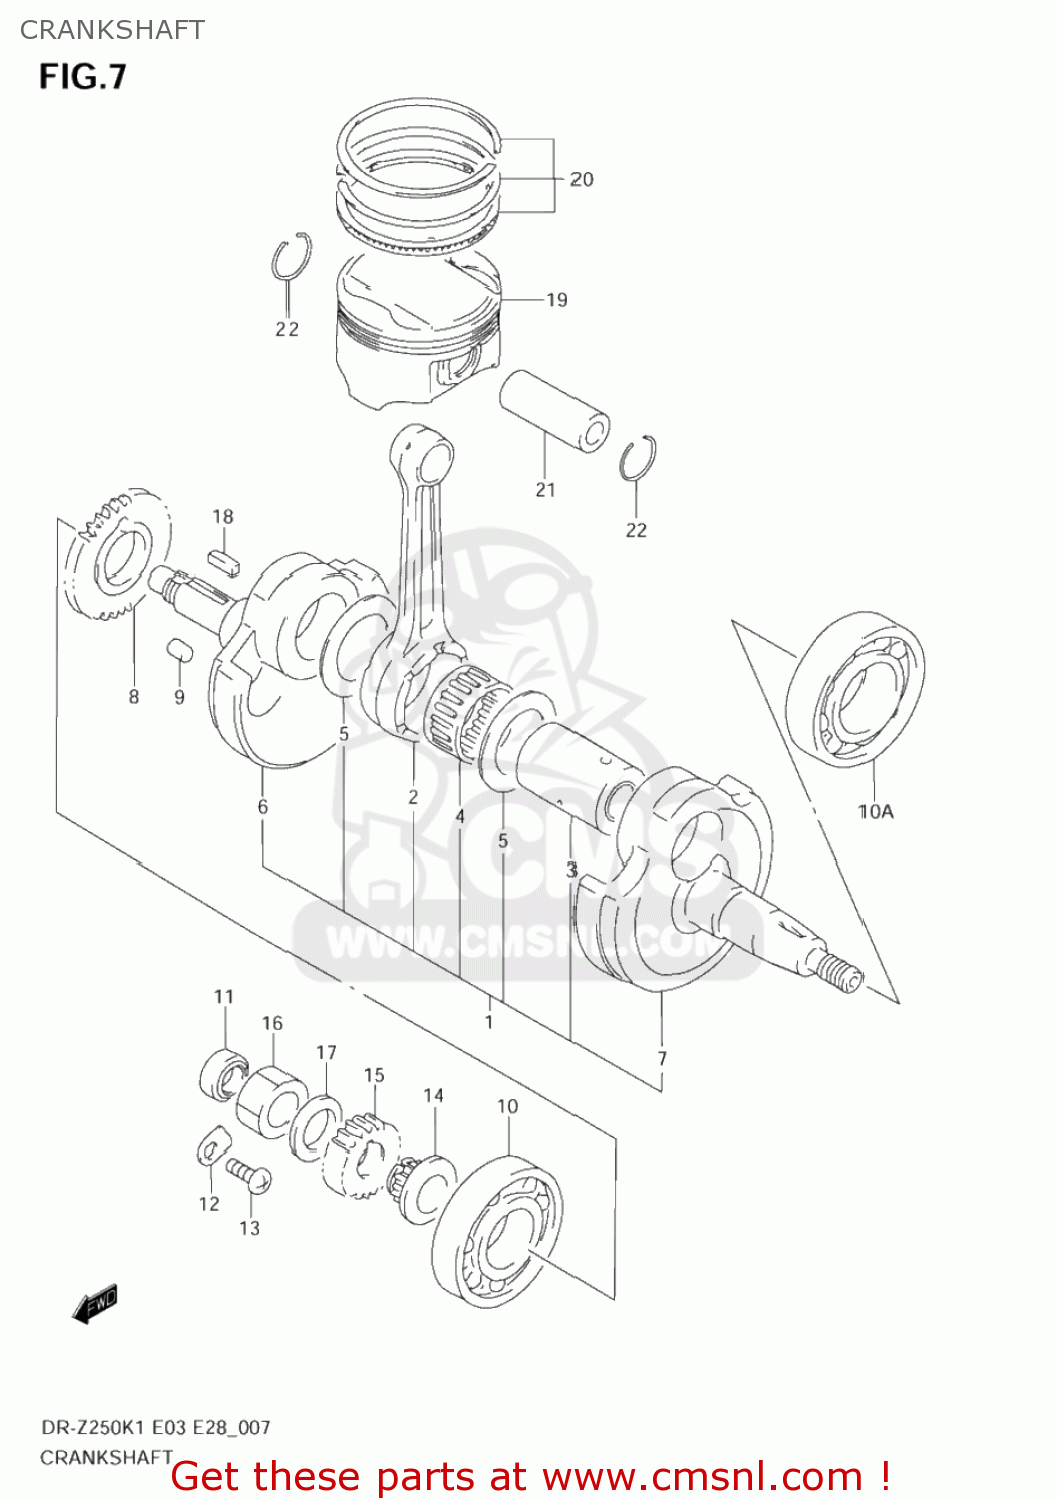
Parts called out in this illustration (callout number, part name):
1	CRANKSHAFT ASSY
2	CONNECTING ROD
3	PIN,CRANK
4	BEARING(34X43X20)
5	WASHER(34X52X1)
6	CRANKSHAFT,R
7	CRANKSHAFT,L
8	GEAR,CRANK BALANCER DRIVE
9	PIN(8X22.5)
10	BEARING(28X68X18)
10A	BEARING(28X68X18)
11	SEAL,OIL(14X24X6)
12	RETAINER,BEARING
13	SCREW
14	SPROCKET,CAM CHAIN DRIVE
15	GEAR,PRIMARY DRIVE
16	NUT
17	WASHER
18	KEY
19	PISTON
20	RING SET,PISTON
21	PIN,PISTON
22	RING,SNAP
